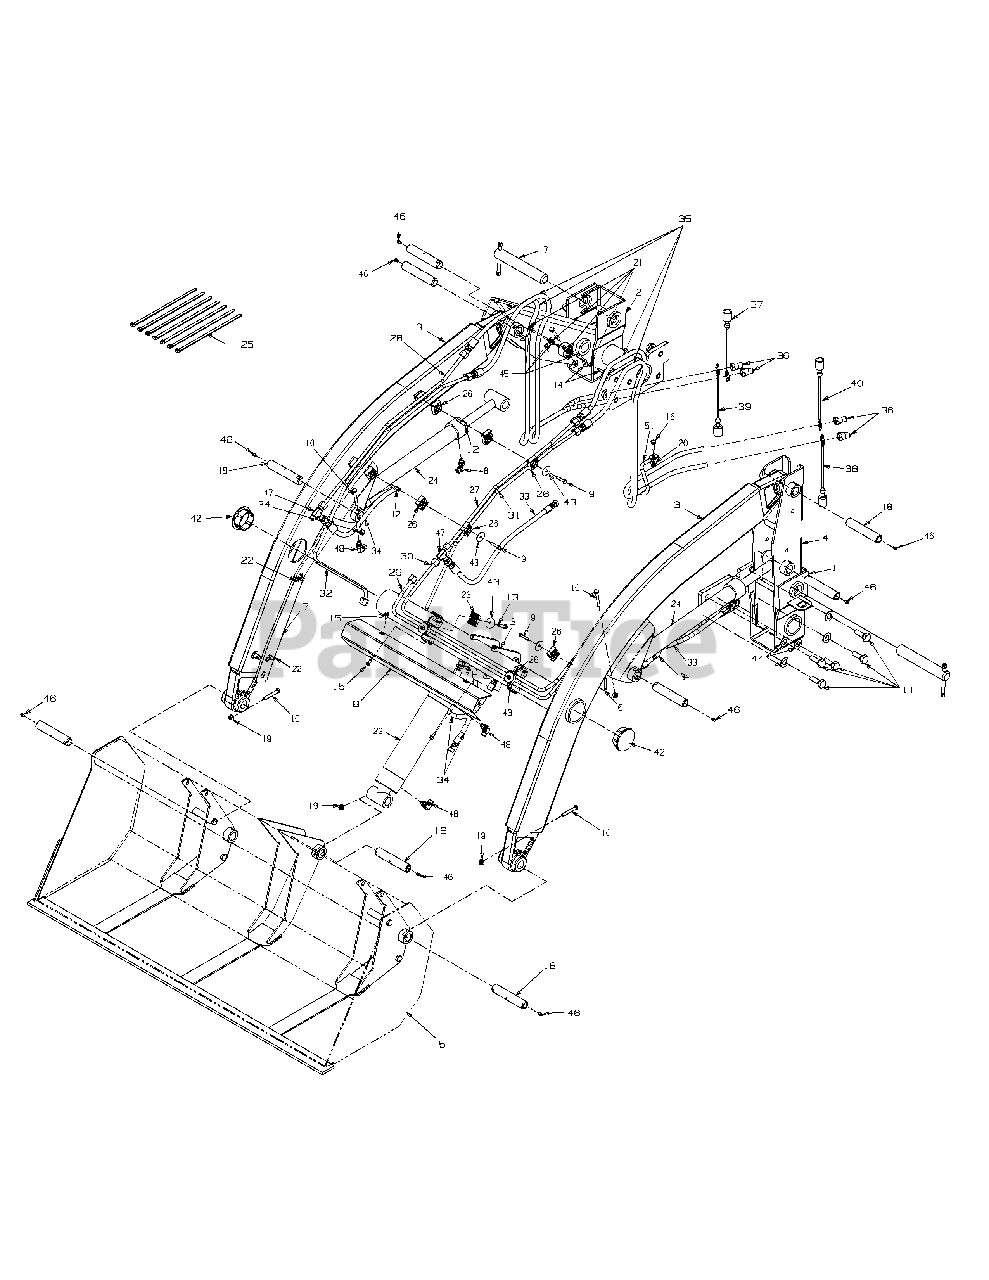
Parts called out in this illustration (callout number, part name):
1	LH Mount Assembly
2	RH Mount Assembly
3	Main Arm Assembly
4	Vertical Support Assembly
5	Bucket Assembly
6	Loader Stand
7	Loader Stand
8	Hydro Line Cover
9	Hex Screw, 1/4-20 x 1.25
10	Hex Screw, 5/16-18 x 2.25
11	Hex Screw, M16-2 x 40 mm
12	Stacking Bolt, 1/4-20 x 3/4
13	Hex Washer Screw, 1/4-20 x 1.500
14	Eye Bolt, 1/4-20
15	Hex Washer Screw, 1/4-20 x .625
16	Hex Screw, M8-1.25 x 25.0
18	Pin, 1" OD x 5"
19	Flange Lock Nut, 5/16-18
20	Flange Lock Nut, M8-1.25
21	Hex Nut, 1/4-20
22	Cotter Pin, .080 x 1.5625
23	Cylinder, 15.5 x 2.5
24	Cylinder, 24.25 x 1.5
25	Cable Tie
26	Tube Clamp
27	Hydraulic Tube
28	Hydraulic Tube
29	Hydraulic Tube
30	Hydraulic Tube
31	Hydraulic Tube
32	Hydraulic Tube
36	Hydraulic Coupling, 9/16-18
37	Green Female Plug, 1/4
38	Yellow Female Plug, 1/4
39	Blue Female Plug, 1/4
40	Red Female Plug, 1/4
43	Flat Washer, .285 x 1.25 x .06
44	Flat Washer, .690 x 1.250 x .075
45	Flat Washer, .25 x .630 x .0515
46	Grease Fitting
47	Hydraulic Swivel Tee Fitting
48	Hydraulic Fitting
